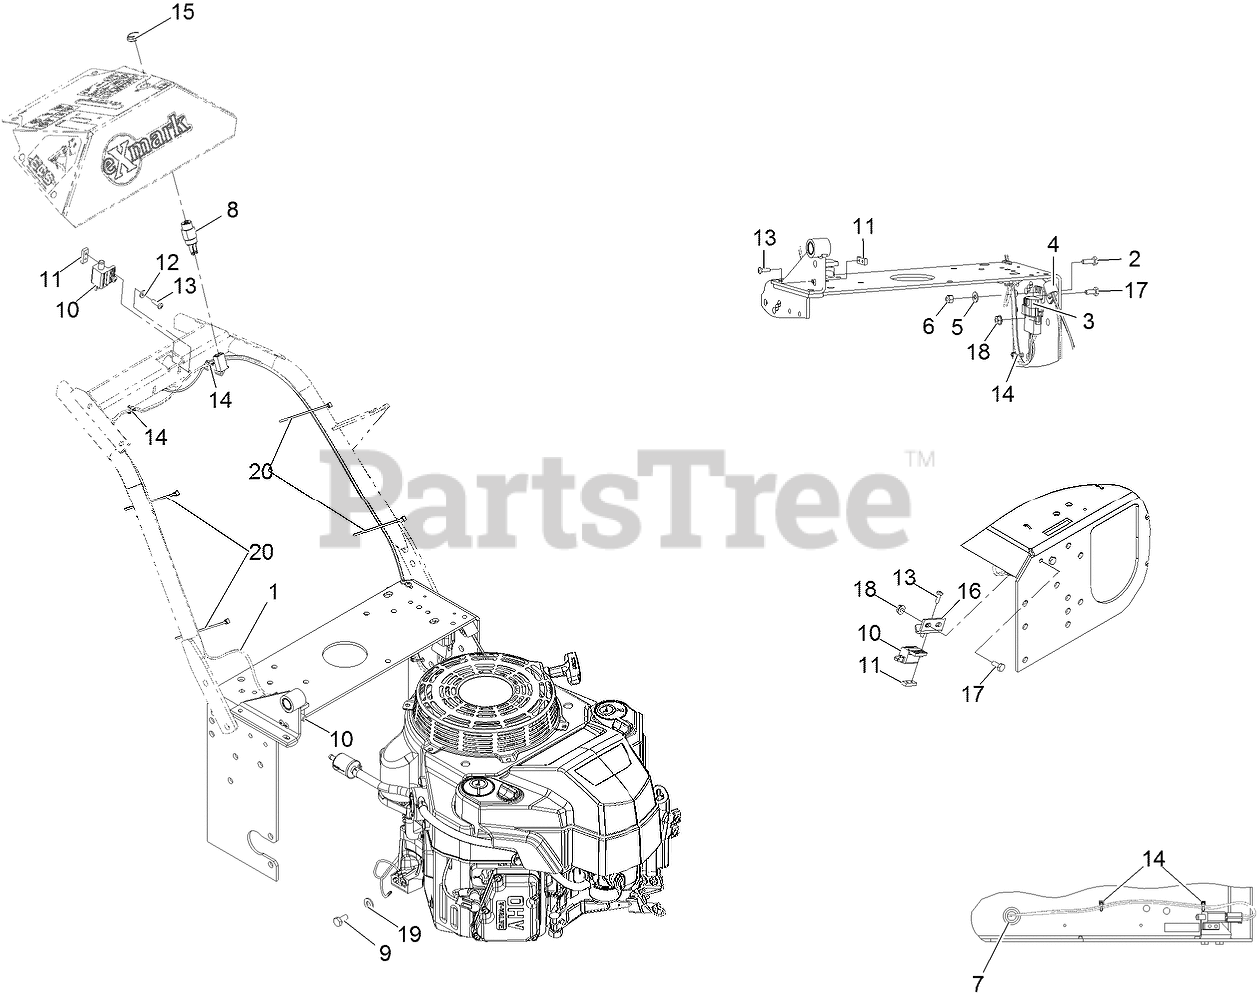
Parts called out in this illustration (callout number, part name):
1	HARNESS-WIRING
2	SCREW-HH
3	MODULE-INTERLOCK
4	CLIP-LOOM
5	WASHER-FLAT
6	NUT-LOCK, NI
7	GROMMET
8	SWITCH & KEY (INCLUDES NU
9	SCREW-HH
10	SWITCH-OPEN, NORMALLY
11	PLATE-TAPPED
12	WASHER-FLAT
13	SCREW-PPH
14	TIE-CABLE
15	NUT-SWITCH, IGNITION
16	BRACKET-SWITCH, BLADE
17	SCREW-HH
19	WASHER-PLAIN
20	TIE-CABLE
